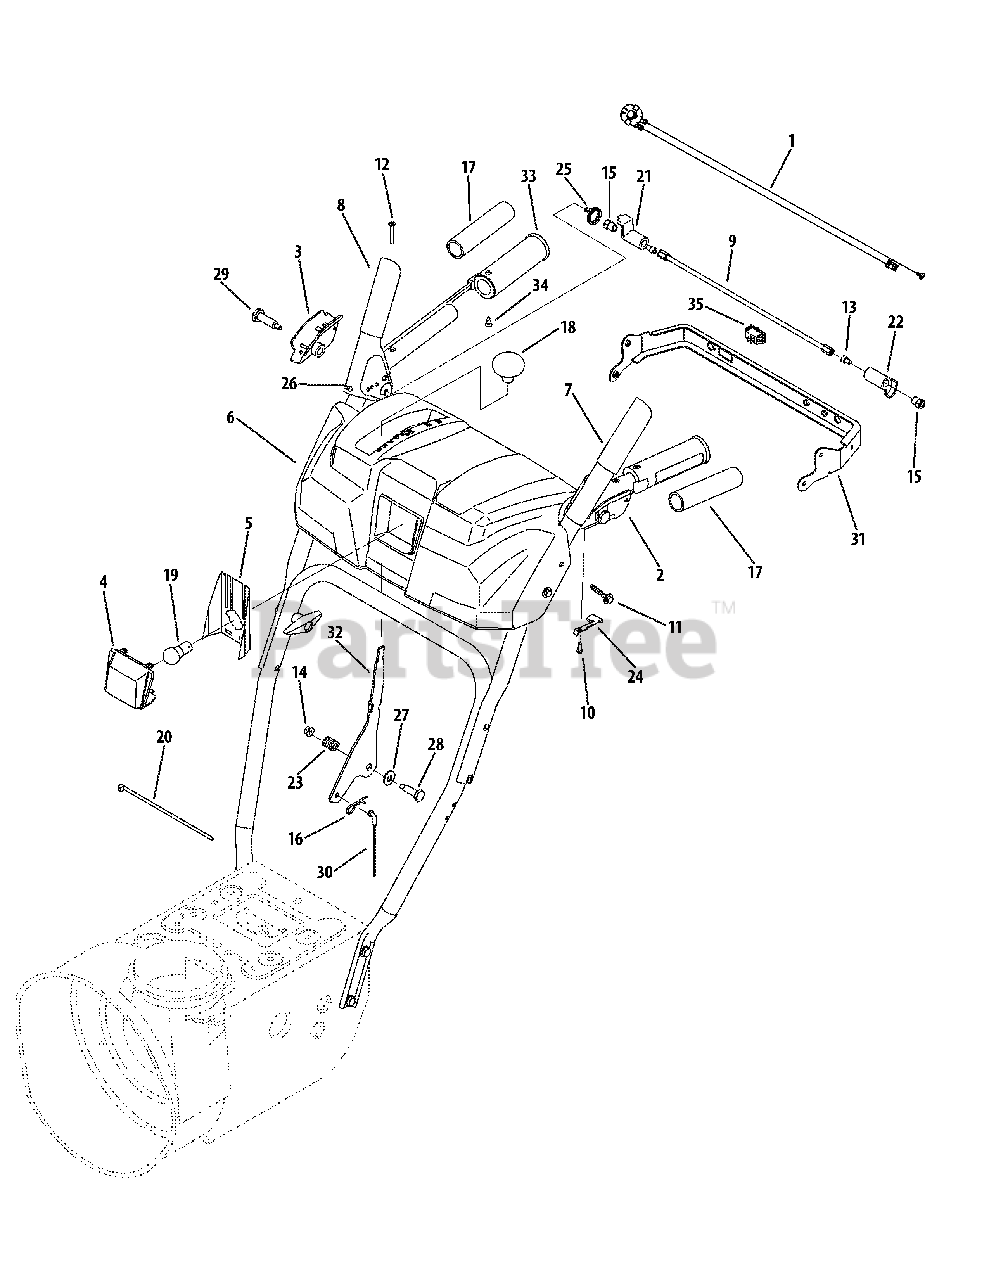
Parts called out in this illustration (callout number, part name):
1	Wire Harness
2	Clutch Lock Handle Assembly, LH
3	Clutch Lock Handle Assembly, RH
5	Lens Label
6	Troy-Bilt Handle Panel
7	Engagement Assembly, LH
8	Engagement Assembly, RH
9	Clutch Pivot Lock Rod Assembly
10	Plastic Screw, #8-16 x .50
11	Hex Washer Screw, 1/4-20 x 1.625
12	Screw, #10-24 x 1.375
13	Socket Screw, 1/4-20 x .50
14	Flange Lock Nut, 1/4-20
15	Hex Nut, 1/4-20
16	Click Pin, .092 x 1.64
17	Grip, 1.0 x 5.0
18	Shift Knob
19	Lamp
20	Cable Tie
22	Clutch Lock
23	Compression Spring .39 x .60 x .88
24	Clutch Lock Spring
25	Torsion Spring, .80156 ID x .3038
26	Rubber Bumper, .62 OD x .22
27	Flat Washer, .385 x .87 x .06
28	Shoulder Screw, .374 x 1.05
29	Shlder. Screw, .437 x 1.345 x 1/4-20
30	Speed Selector Cable
33	Heated Grip
34	Screw, #10-16 x .625
35	Heated Grip Switch
